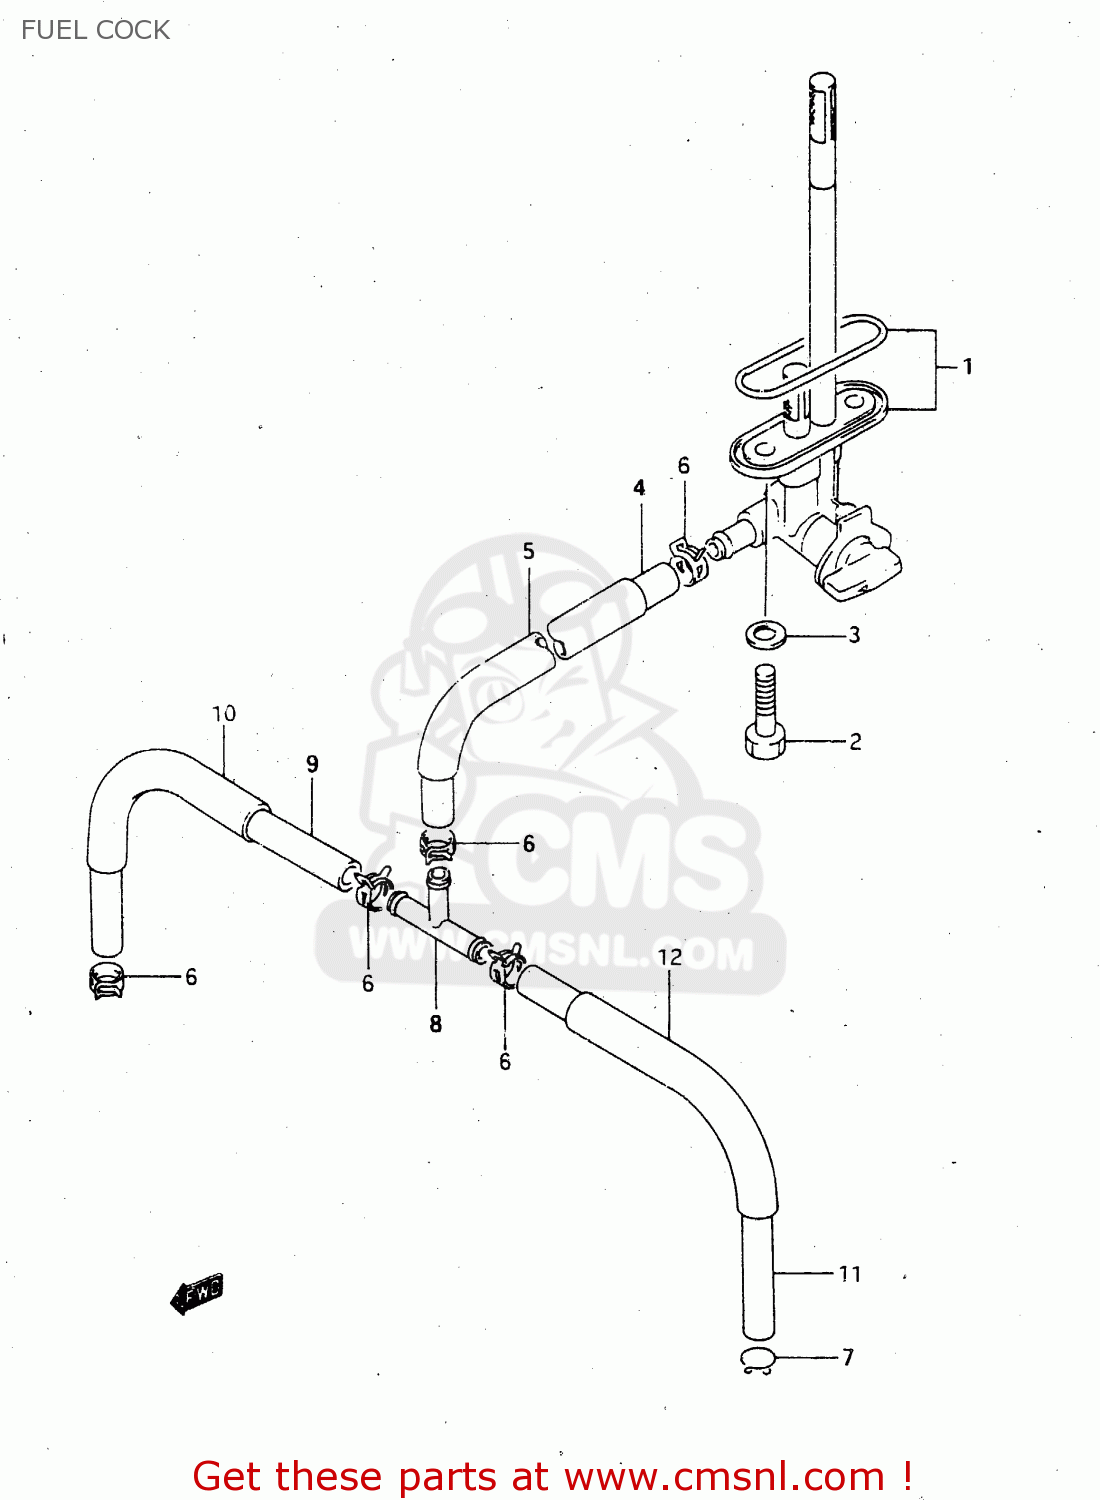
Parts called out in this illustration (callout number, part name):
1	COCK ASSY,FUEL
2	BOLT(6X20)
3	GASKET(6.4X11.5X0.8) (NAS)
4	HOSE(7X11X600)
5	HOSE(13.5X16.5X600)
6	CLIP
7	CLIP
8	3-WAY [FILTER TO PUMP)
9	HOSE(7X11X600)
10	HOSE(13.5X16.5X600)
11	HOSE(7X11X600)
12	HOSE(13.5X16.5X600)
